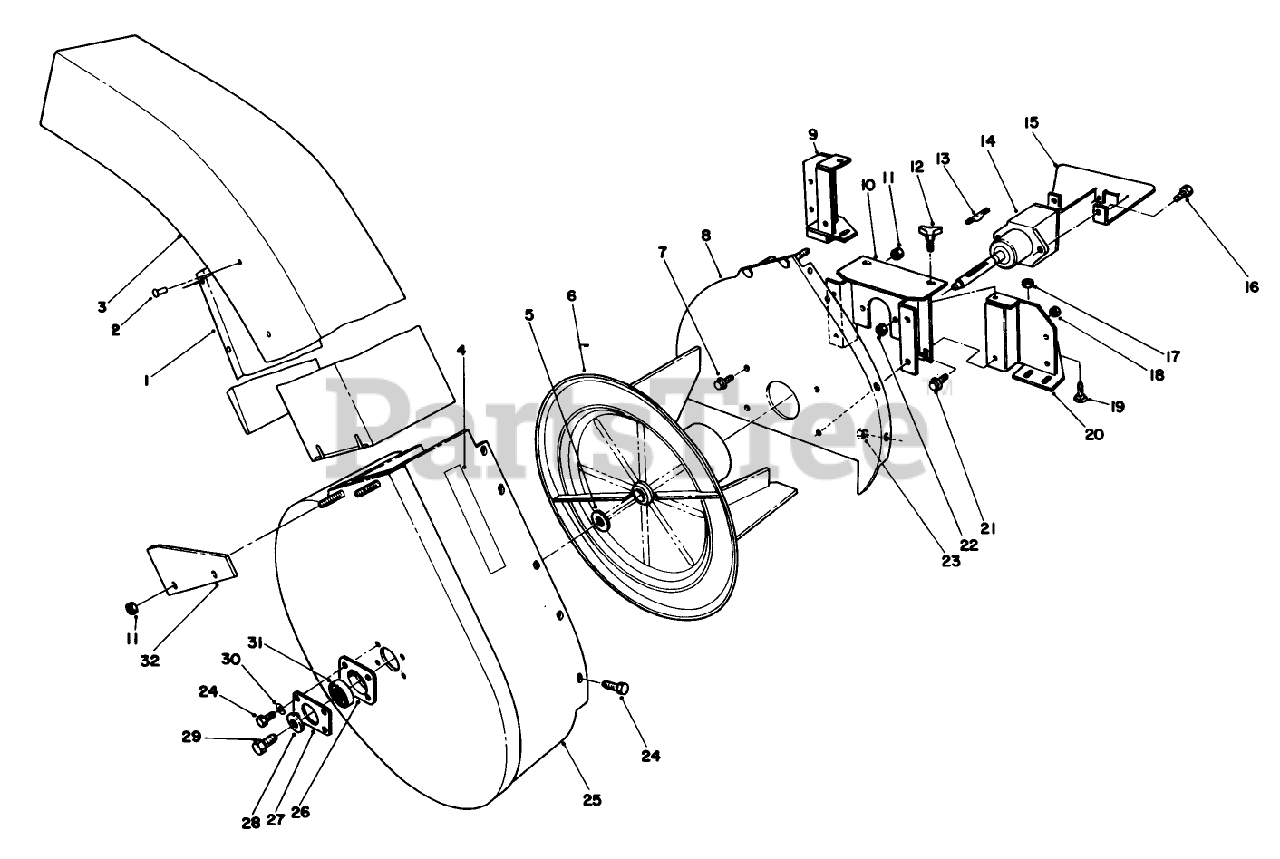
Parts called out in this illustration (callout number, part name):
1	Deflector
3	Chute Assembly (Incl. Ref. #1 & 2)
4	Decal-Waming
5	SPACER-BEARING
6	Impeller
7	SCREW-HHF
8	Mounting Plate
9	L/H BLOWER MT/NUT ASM
10	Blower Mount
11	NUT-LOCK, NI
14	Gear Box Assembly
15	Cover-Gear Box
16	SCREW-HH
17	NUT-KEPS
18	NUT-JAM
19	SCREW-CARR
20	RH BLWR MT BRKT WA
21	SCREW-HHF
22	NUT-LOCK, NI
23	NUT-LOCK, NI
24	SCREW-HH
25	BLOWER HOUSING ASM
26	CUP-BEARING
27	Cover-Plate
28	SPACER
29	SCREW-HH, LOCK
30	WASHER-LOCK
31	BEARING-BALL
32	Bracket
